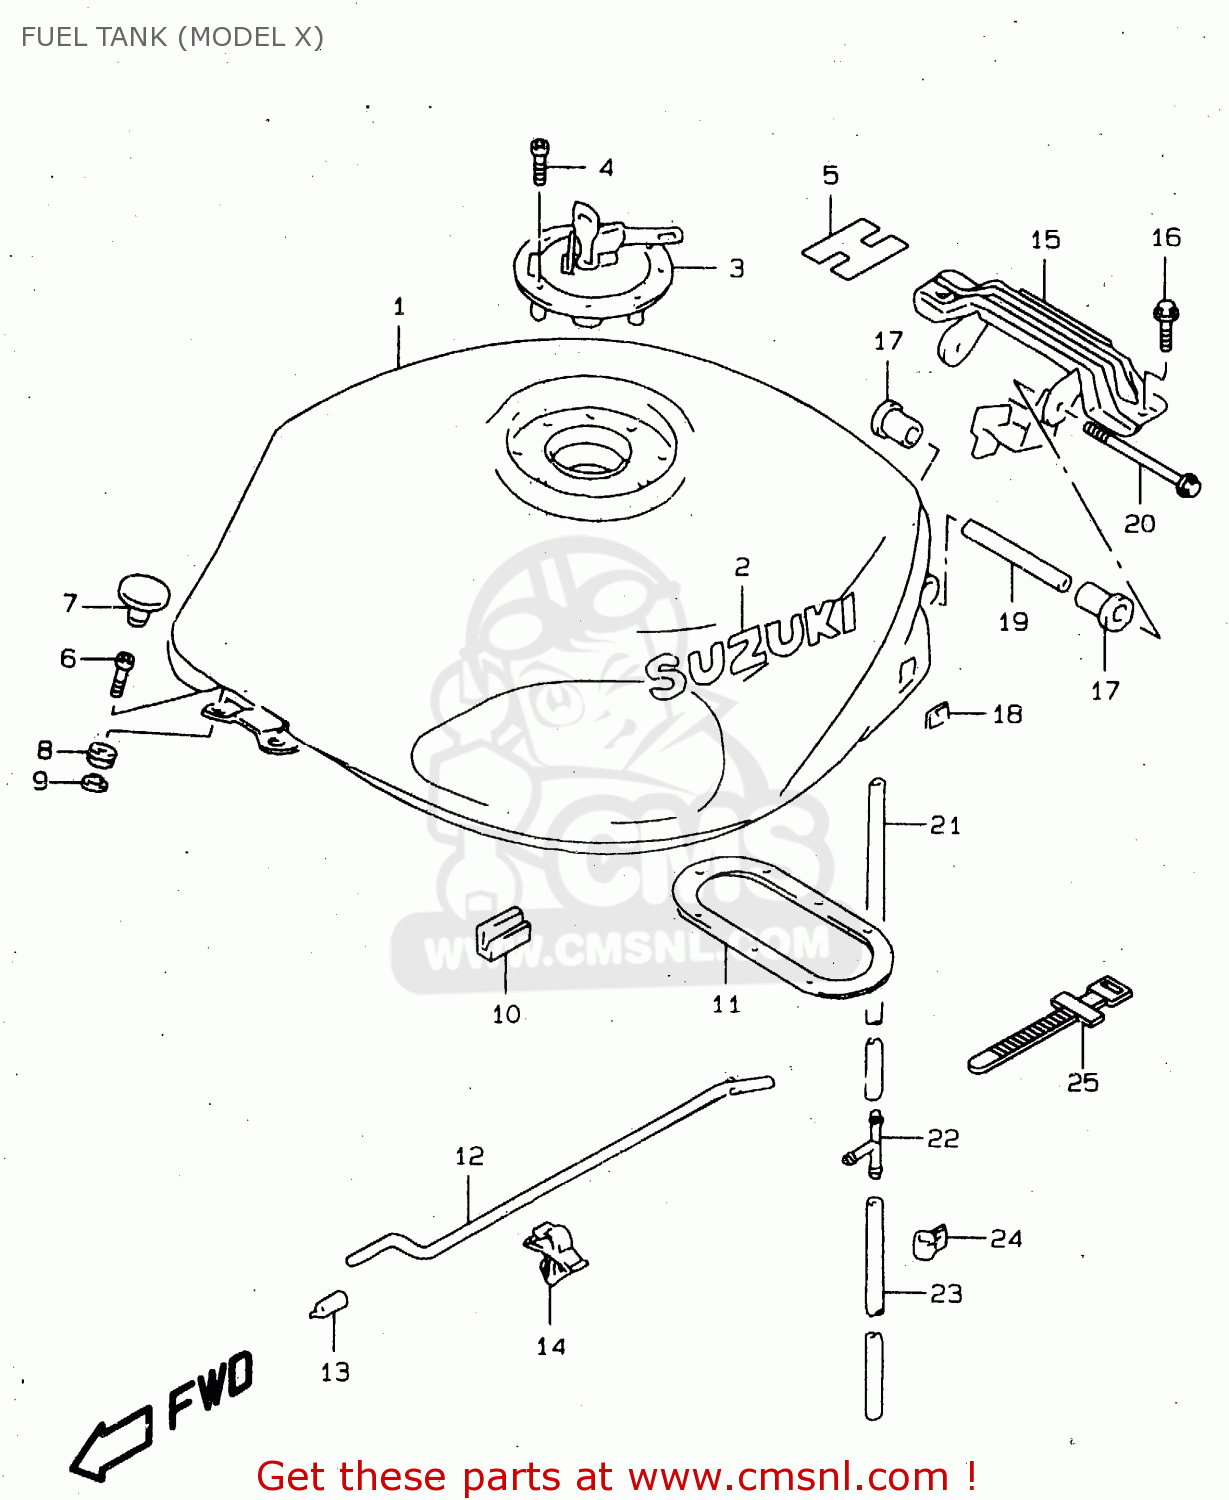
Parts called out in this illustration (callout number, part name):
1	TANK ASSEMBLY,FUEL
2	EMBLEM,FUEL TANK
3	CAP SET,FUEL TANK
4	BOLT(5X20)
5	LABEL,FUEL TANK INNER
6	BOLT
7	CAP,BOLT
8	CUSHION
9	WASHER
10	CUSHION,FUEL TANK SIDE
11	GASKET,FUEL PUMP (NAS)
12	STAY,FUEL TANK
13	CAP,OD:11
14	CLAMP
15	BRACKET,FUEL TANK,REAR
16	BOLT(8X16)
17	CUSHION,FUEL TANK RR
18	FASTENER,FUEL TANK
19	SPACER,FUEL TANK RR
20	BOLT
21	HOSE,FUEL TANK DRAIN
22	3 WAY
23	HOSE(7X10.2X600)
24	CLAMP
25	CLAMP(L:125)
